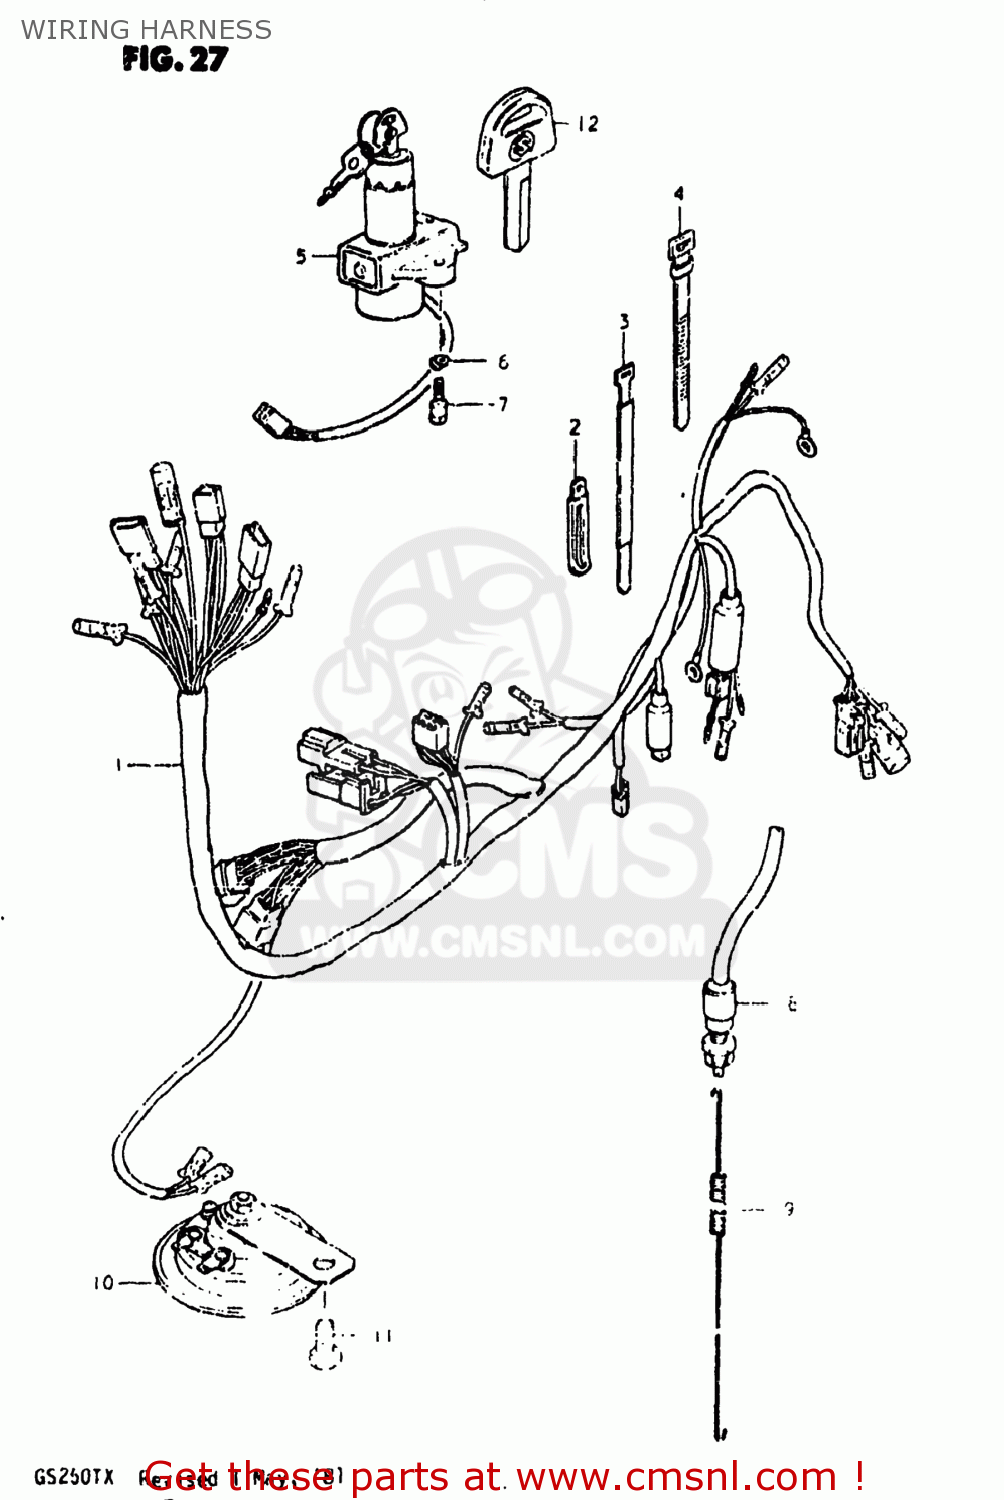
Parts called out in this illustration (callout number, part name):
1	HARNESS,WIRING
2	CLAMP
3	CLAMP
4	CLAMP(L:80)
5	SWITCH ASSEMBLY,IGNITION
6	BOLT
7	LOCK WASHER
8	SWITCH ASSEMBLY,STOP LAMP
9	SPRING
10	HORN ASSEMBLY
11	BOLT 8X12
12	KEY,BLANK
